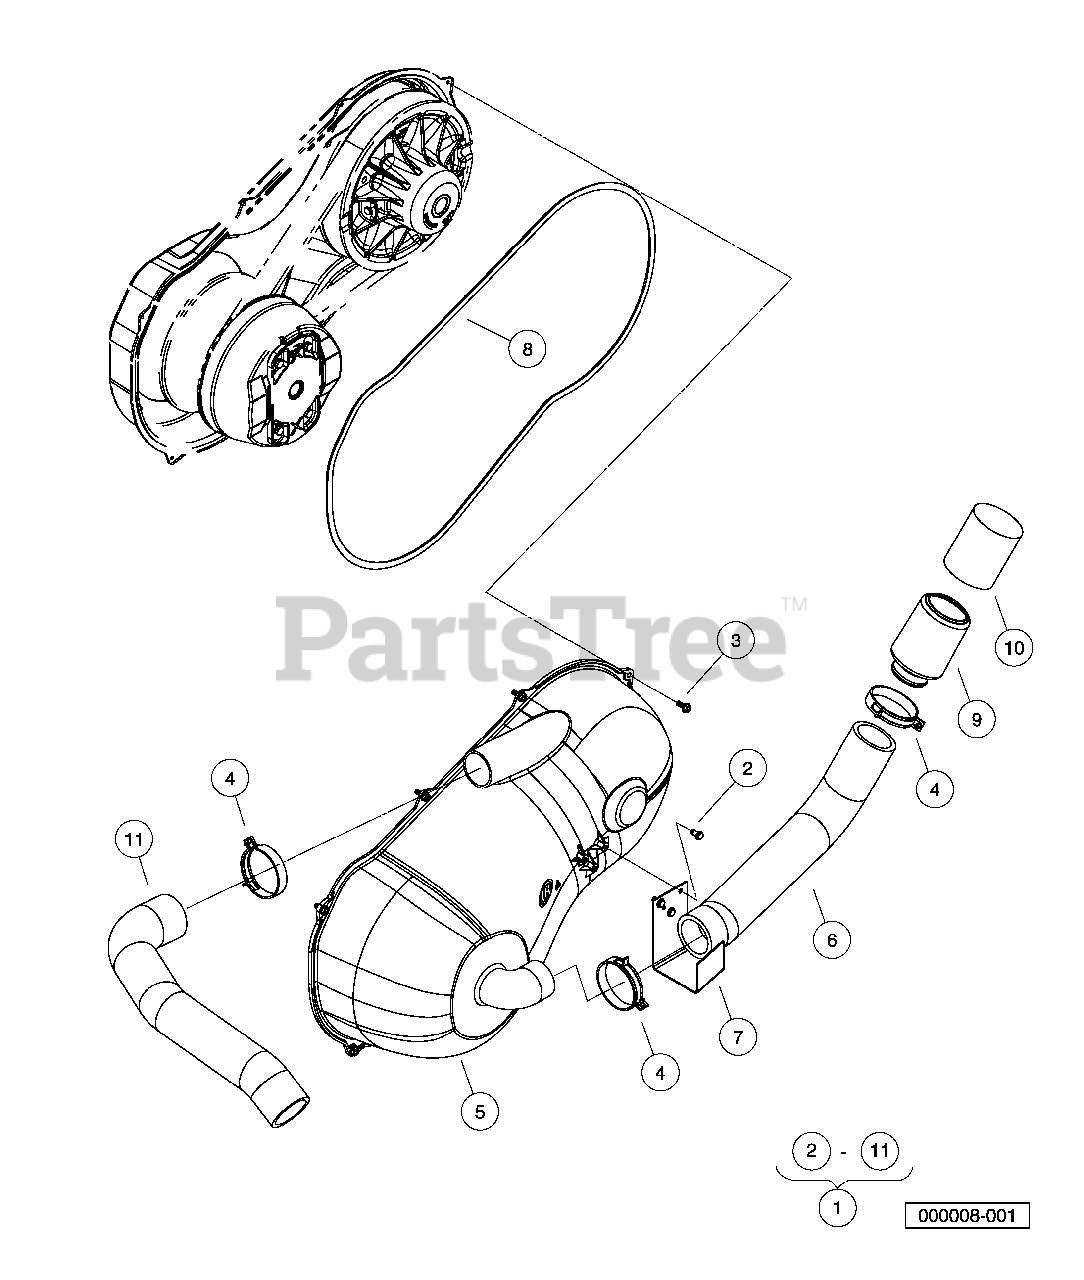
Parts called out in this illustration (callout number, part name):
1	Kit, Sealed CVT Cover
2	Screw, 1/4-15 X 1.50 Hi-lo Hex
3	Screw, M6 X 16 Tt Hx Fl Hd
4	Clamp, Hose, Ctb 64mm
5	Cover, CVT Outer
6	Hose, Inlet, Cover, CVT
7	Bracket, Inlet, Cover, CVT
8	Gasket, Cover, CVT
9	Cap, Inlet, Cover, CVT
10	Filter, Inlet, Cover, CVT
11	Hose, Outlet, Cvt
